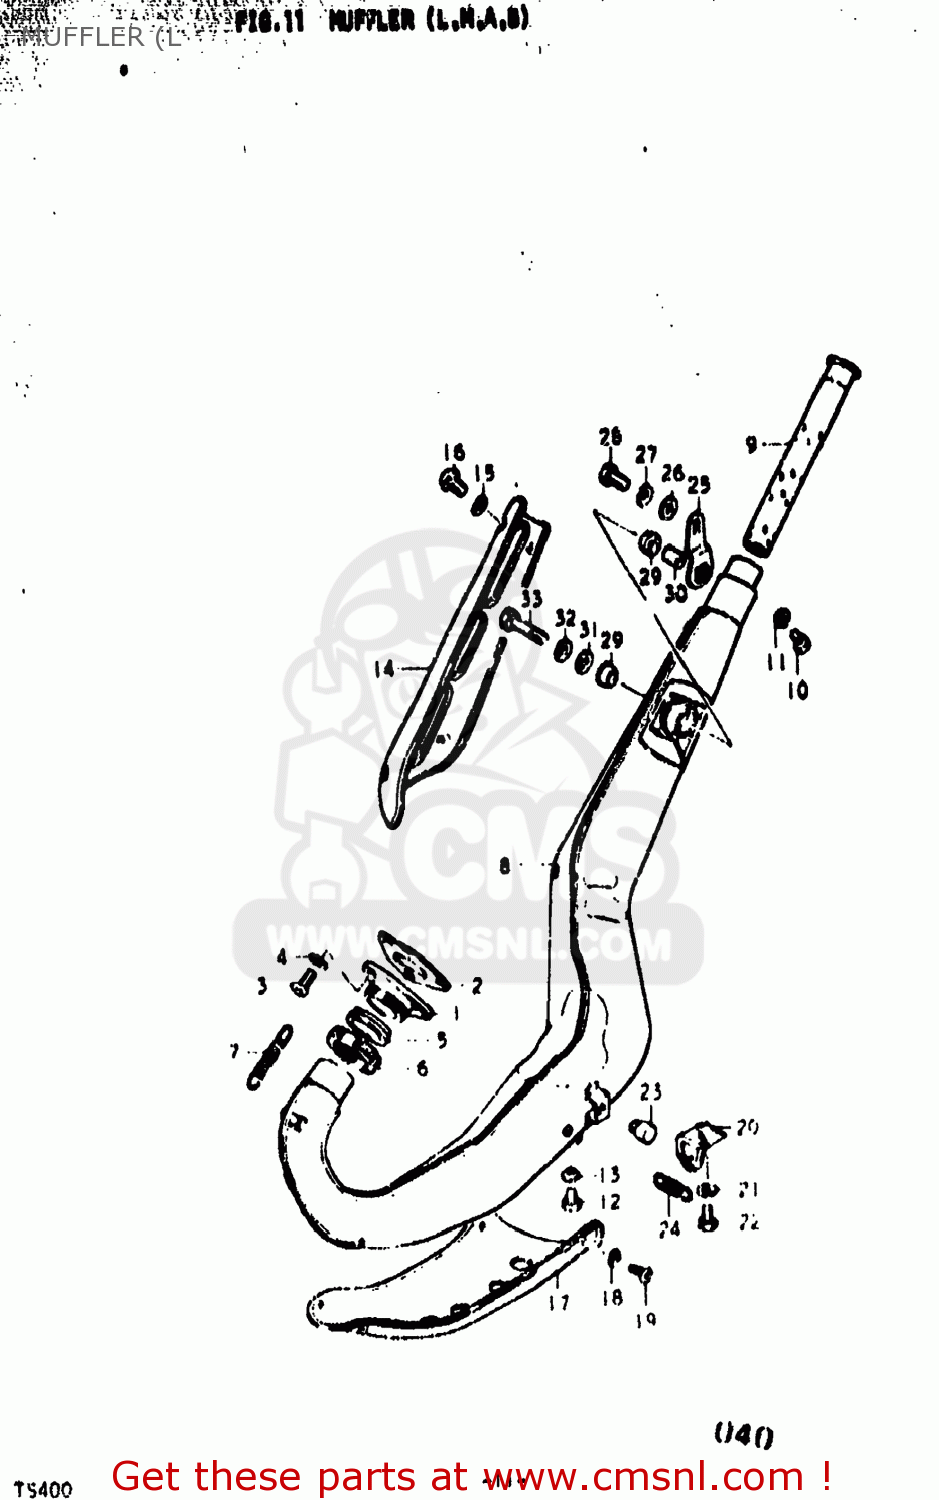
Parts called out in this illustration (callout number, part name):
1	FLANGE,EXHAUST PIPE
2	GASKET,EXHAUST PIPE (MCA)
3	SCREW
4	LOCK WASHER
5	CLAMP,EXHAUST PIPE
6	HOLDER,EXHAUST PIPE CLAMP
7	SPRING
8	MUFFLER ASSEMBLY
9	PIPE,MUFFLER BAFFLE
10	SCREW(6X8)
11	LOCK WASHER
12	PLUG
13	GASKET(10X14X3.6) (NAS)
14	COVER,MUFFLER
15	LOCK WASHER
16	SCREW
17	COVER,MUFFLER
18	LOCK WASHER
19	SCREW
20	BRACKET, MUFFLER STOPPER
21	LOCK WASHER
22	BOLT
23	CUSHION(11.5X22X20)
24	SPRING
25	BRACE,MUFFLER
26	WASHER
27	LOCK WASHER
28	BOLT
29	CUSHION
30	SPACER (8.2X12.5X23.5)
31	WASHER (8.7X22X2)
32	LOCK WASHER
33	BOLT 8X40
